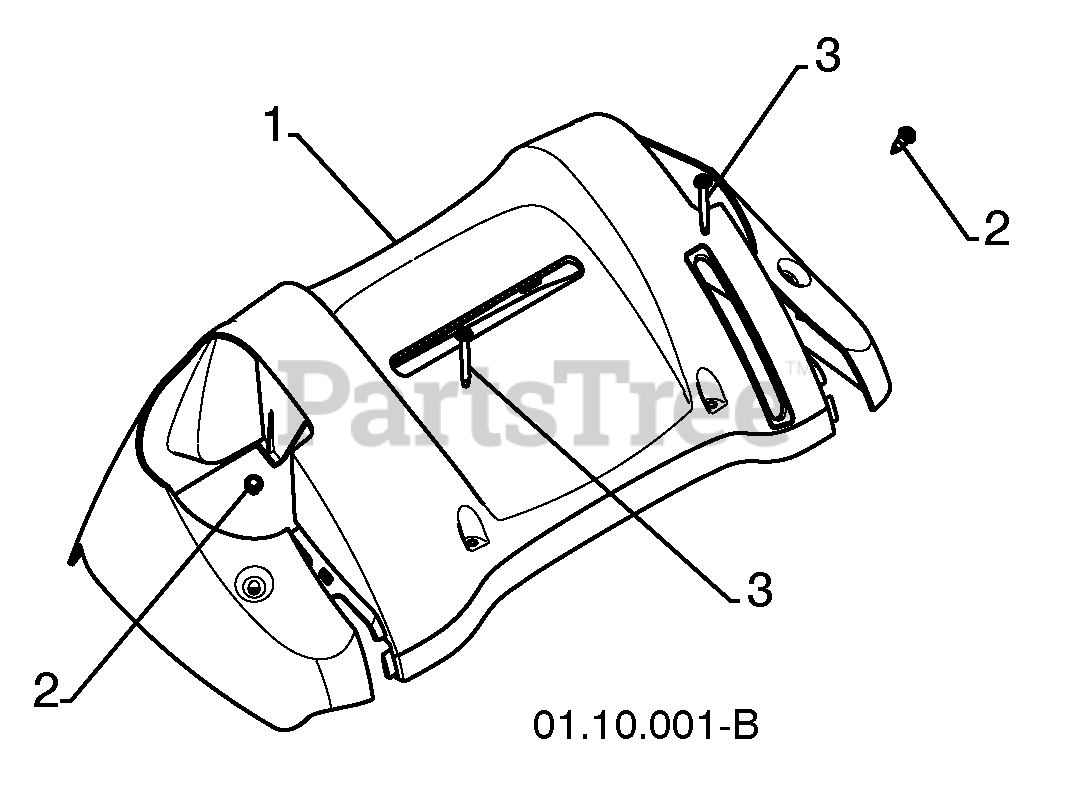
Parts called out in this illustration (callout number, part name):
1	CONSOLE PANEL
2	SCREW 10-24 X .625
3	SCREW 10-24 X 1.25
